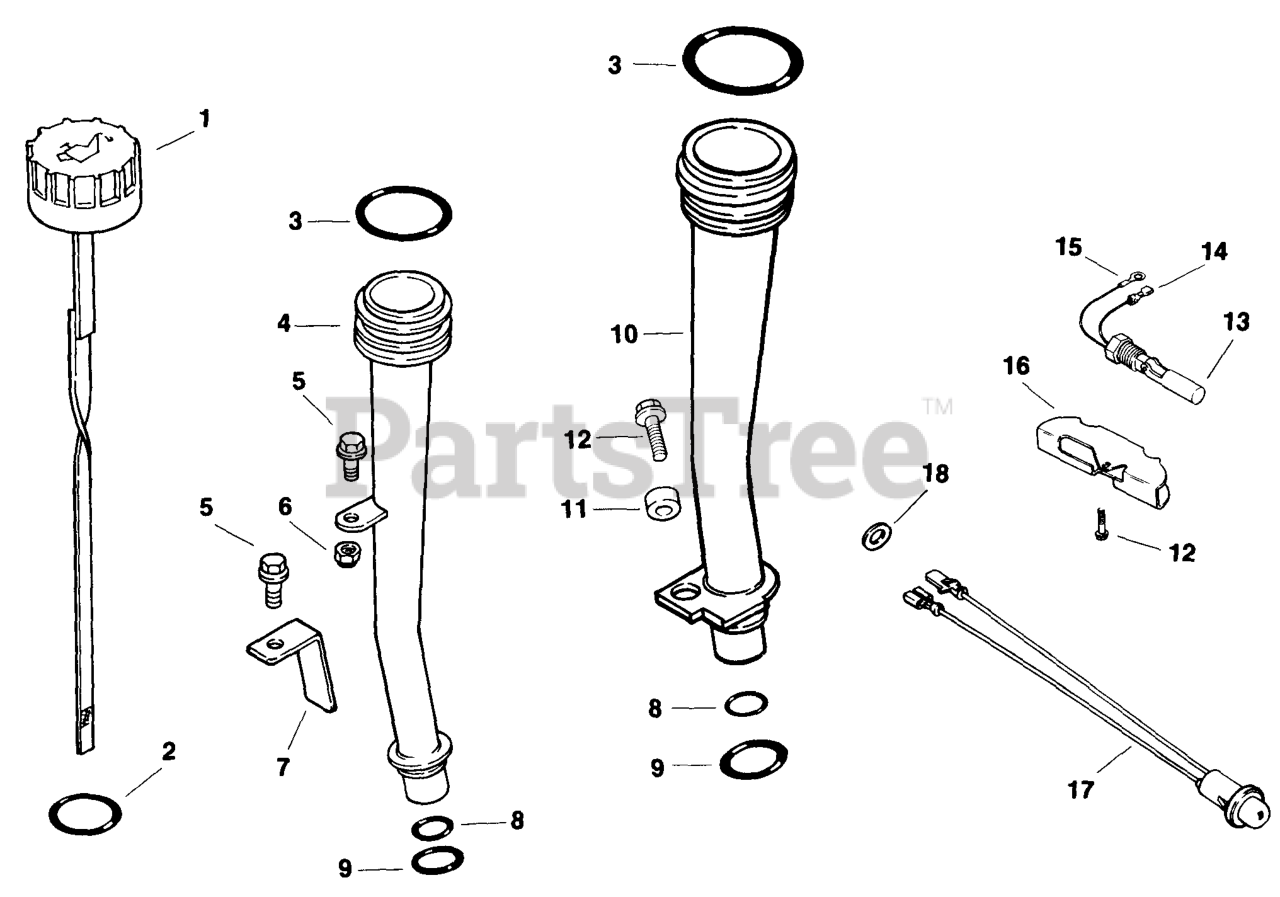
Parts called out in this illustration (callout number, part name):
3	O-RING, UPPER OIL FILL TUBE
10	TUBE - DISCONTINUED
11	SPACER
12	SCREW - USE M-545016
13	SWITCH, OIL LEVEL - DISC.
15	TERMINAL - DISCONTINUED
16	BAFFLE, OIL SENTRY - DISC.
17	LIGHT, INDICATOR
18	WASHER,INT EXT TOOTH LOCK 5/16"
